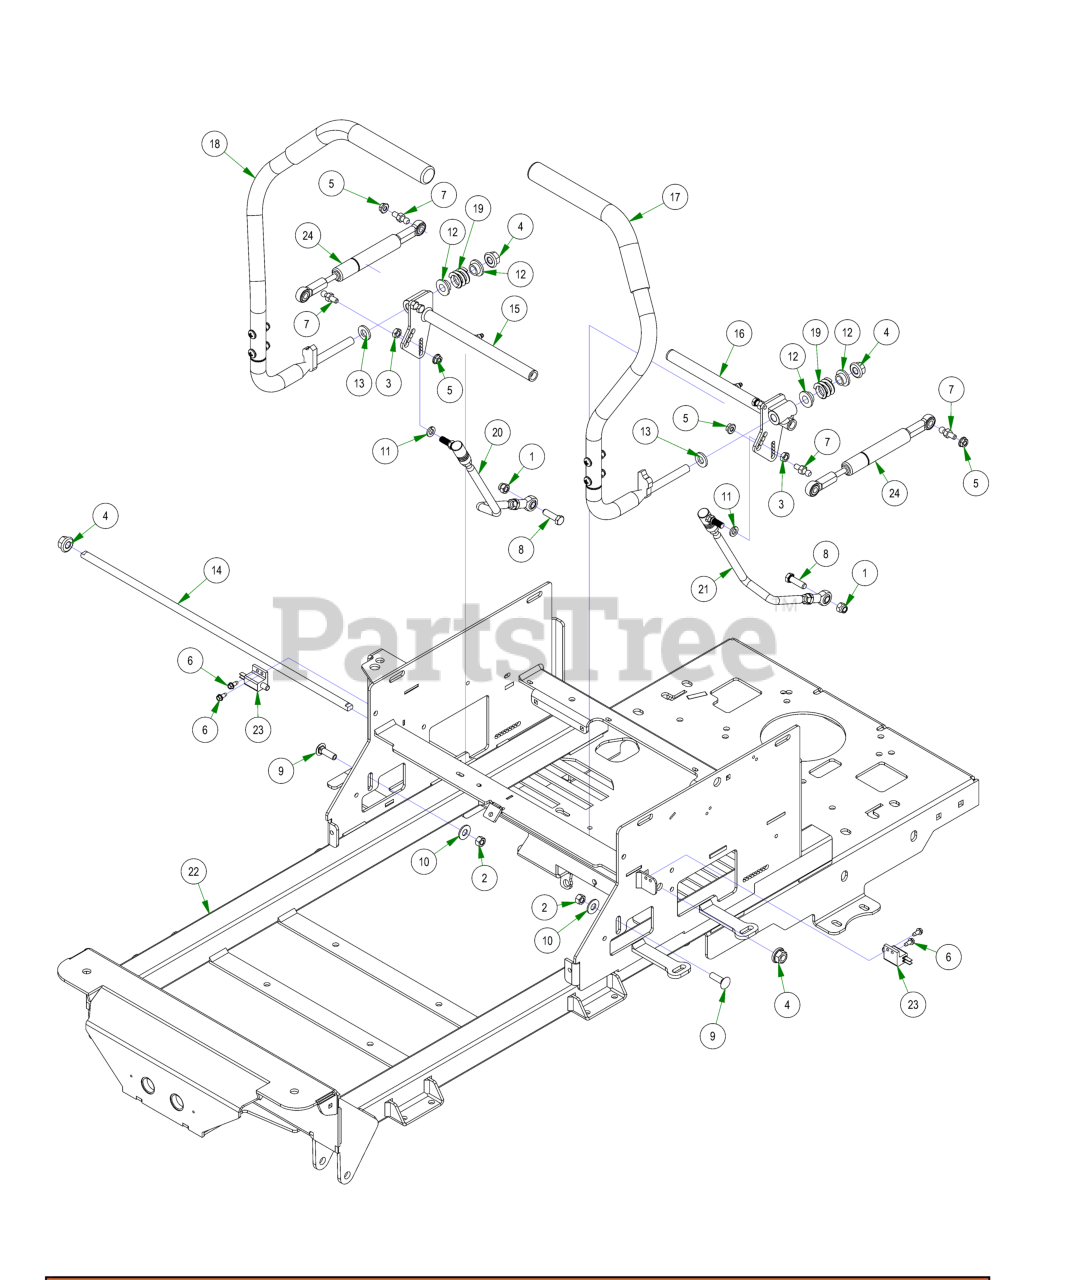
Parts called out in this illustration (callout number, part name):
1	3/8-16 NYLON INSERT LOCKNUT ZINC
2	3/8-16 HEX NUT ZINC
3	3/8-24 HEX NUT ZINC YELLOW
4	1/2-13 NYLON INSERT FLANGE LOCKNUT ZINC
5	5/16-18 HEX SERRATED FLANGE NUT HARD/ZINC
6	12-24 X 1/2 HEX WASHER UNLSOT F TCS ZINC
7	10mm Damper Ball Stud-Steering
8	3/8-16 X 1-1/4 HEX CAP SCREW (GR.5) ZINC
9	3/8-16 X 1-1/4 CARRIAGE BOLT ZINC
10	3/8 FLAT WASHER USS (1" OD) ZINC
11	3/8 SPLIT LOCKWASHER ZINC
12	.525 ID SHOULDER WASHER NYLON
13	.505 ID X 1.000 OD X .125 THICK FLAT WASHER NYLON
14	2021 Maverick Steering Actuator Rod
15	2021 Maverick Drive Arm Actuator RH Assembly
16	2021 Maverick Drive Arm Actuator LH Assembly
17	ZT Steering Arm-Left
18	ZT Steering Arm-Right
19	Drive Lever Spring
20	Push Rod-Right
21	Push Rod-Left
22	2024 ZT Elite Frame
23	Safety Switch
24	Steering Damper
